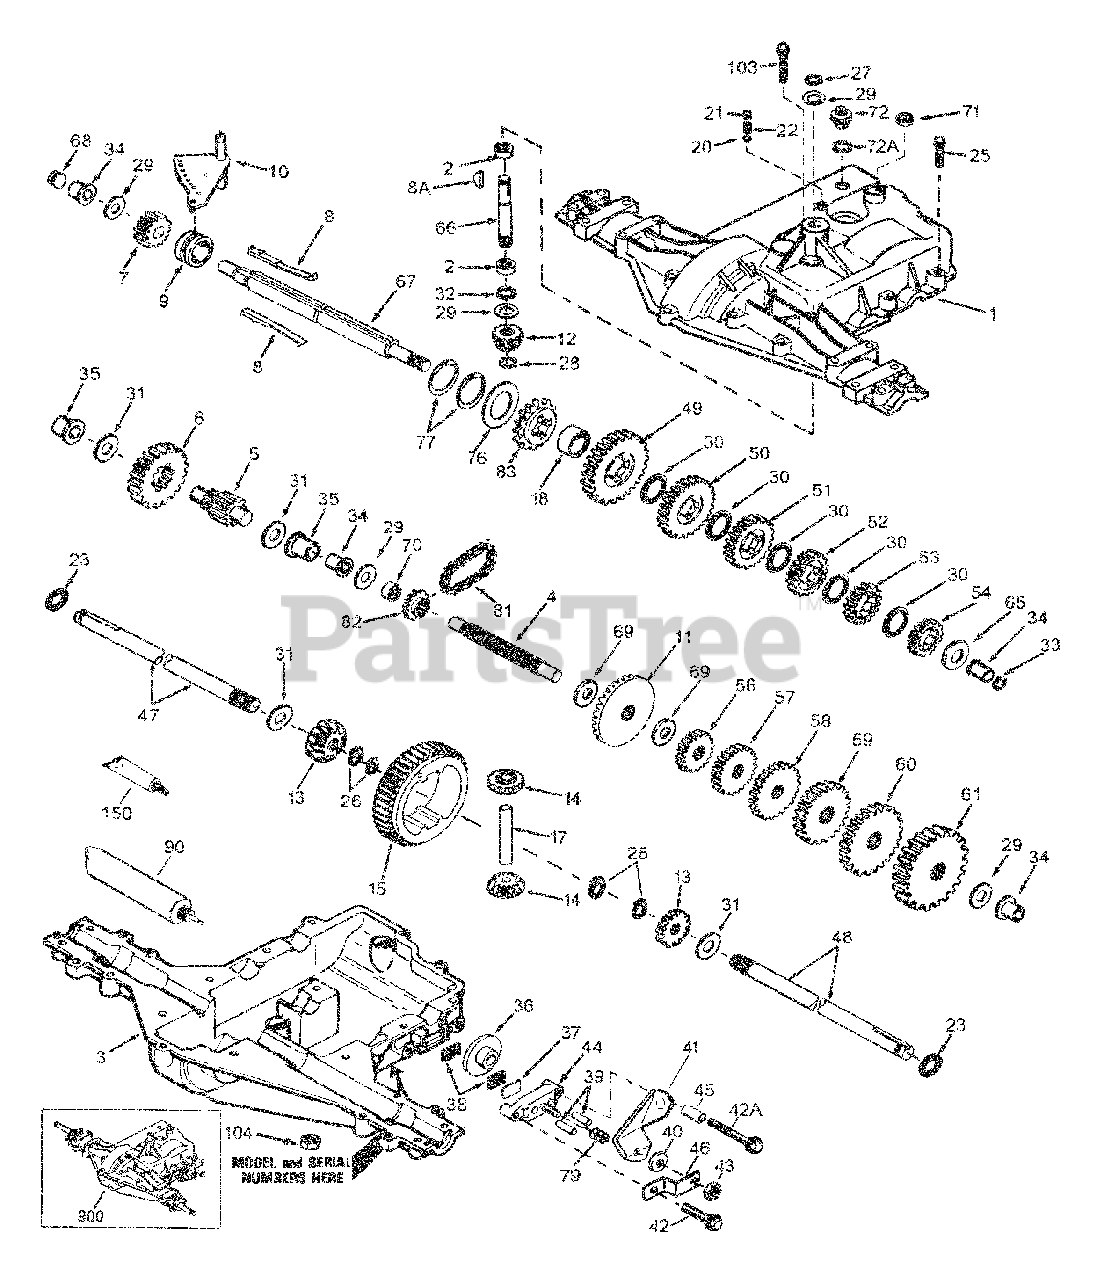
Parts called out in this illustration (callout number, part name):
1	Cover, Transaxle
2	Bearing, Needle
3	Case, Transaxle
4	Shaft, Counter
5	Shaft and Pinion Assembly, Output
6	Gear, Output
7	Gear, Spur, 15 Teeth
8	Key, Shift
8A	Key, Woodruff
9	Collar, Shifter
10	Rod and Fork Assembly, Shift
11	Gear, Bevel, 42 Teeth
12	Bevel Pinion, Input
13	Gear, Bevel
14	Gear, Bevel Pinion
15	Gear, Ring
17	Pin, Drive
18	Spacer, Neutral
20	Ball, Steel 5/16" diameter
21	Set Screw 3/8-16 x 3/8
23	Ring, Seal
25	Screw, Flanged Hex Head, Thread Forming 1/4-20 x 1-1/4
26	Ring, Retainer
27	Ring, Retainer
28	Ring, Retainer
29	Washer, Thrust
30	Washer, Thrust
32	"O" Ring
33	Seal, Square Cut
34	Bushing, Flanged
35	Bushing, Flanged
36	Disk, Brake
37	Plate, Brake Pad
38	Pad, Brake
39	Pin, Dowel
40	Washer, Flat
41	Lever, Brake
42	Screw, Flanged Hex Head, Thread Forming 1/4-20 x 1-1/4
42A	Screw 1/4-20 x 2-1/4
43	Locknut 5/16-24
44	Holder, Brake Pad
46	Bracket, Brake Lever
47	Axle 11-5/16" long
48	Axle 16-1/2" long
49	Gear, Spur, 37 Teeth, Steel (1st)
50	Gear, Spur, 35 Teeth (2nd)
51	Gear, Spur, 30 Teeth (3rd)
52	Gear, Spur, 25 Teeth (4th)
53	Gear, Spur, 22 Teeth (5th)
54	Gear, Spur, 19 Teeth, Steel (6th)
56	Gear, Spur, 12 Teeth (1st)
57	Gear, Spur, 15 Teeth (2nd)
58	Gear, Spur, 20 Teeth (3rd)
59	Gear, Spur, 25 Teeth (4th)
60	Gear, Spur, 28 Teeth (5th)
61	Gear, Spur, 31 Teeth (6th)
65	Washer, Thrust
66	Shaft, Input
67	Shaft, Brake, 4 Keyed
69	Washer, Thrust
71	Seal, Square Cut
72	Plug, Threaded 9/16-18
72A	"O" Ring
76	Washer, Thrust
77	Ring, Retaining, Inverted
79	Spring, Brake
81	Chain, Roller
82	Sprocket, 9 Teeth (Reverse)
83	Sprocket, 18 Teeth (Reverse)
90	Grease, Bentonite, 32 Ounce Bottle
103	Screw 1/4-20 x 2
104	Locknut 1/4-20
150	Gasket Eliminator (Loctite #515)
900	Replacement Transaxle
